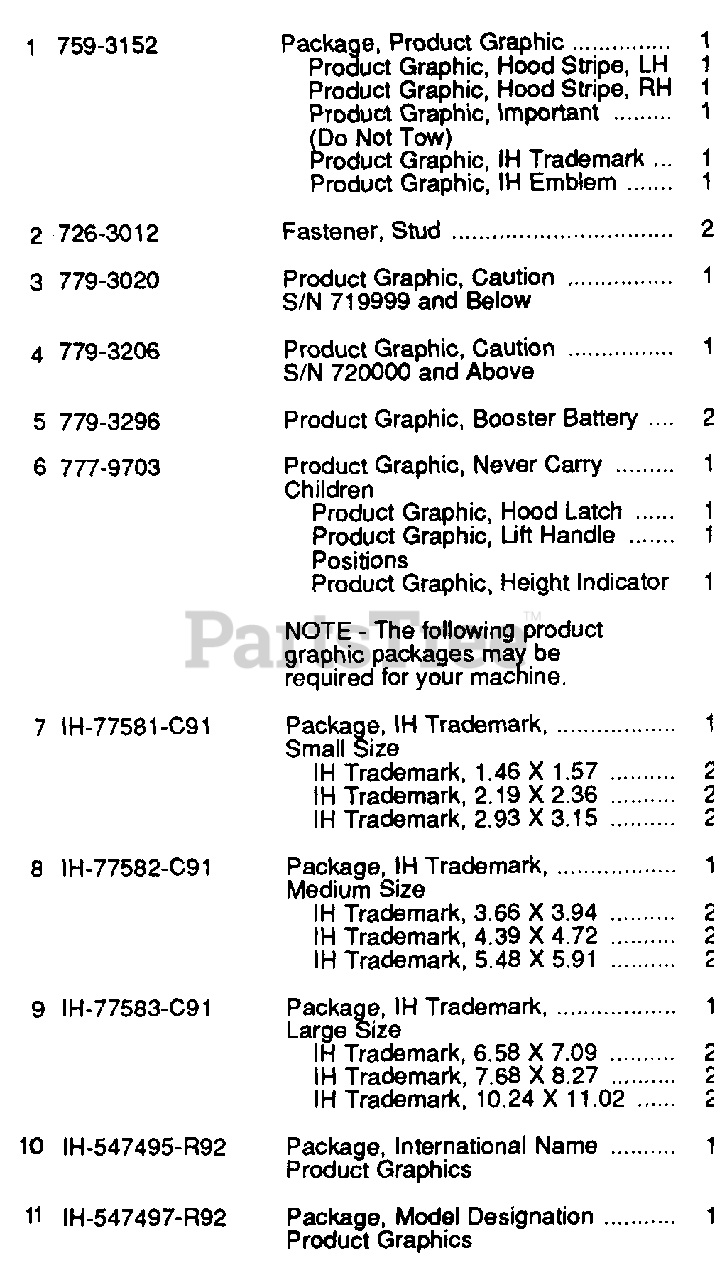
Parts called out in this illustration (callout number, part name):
1	Package, Product Graphic
2	Fastener, Stud
3	Product Graphic, Caution S/N 719999 and Below
4	Product Graphic, Caution S/N 720000 and Above
5	Product Graphic, Booster Battery
6	Product Graphic, Never Carry Children
7	Package, IH Trademark, Small Size
8	Package, IH Trademark, Medium Size
9	Package, IH Trademark, Large Size
10	Package, International Name Product Graphics
11	Package, Model Designation Product Graphics
